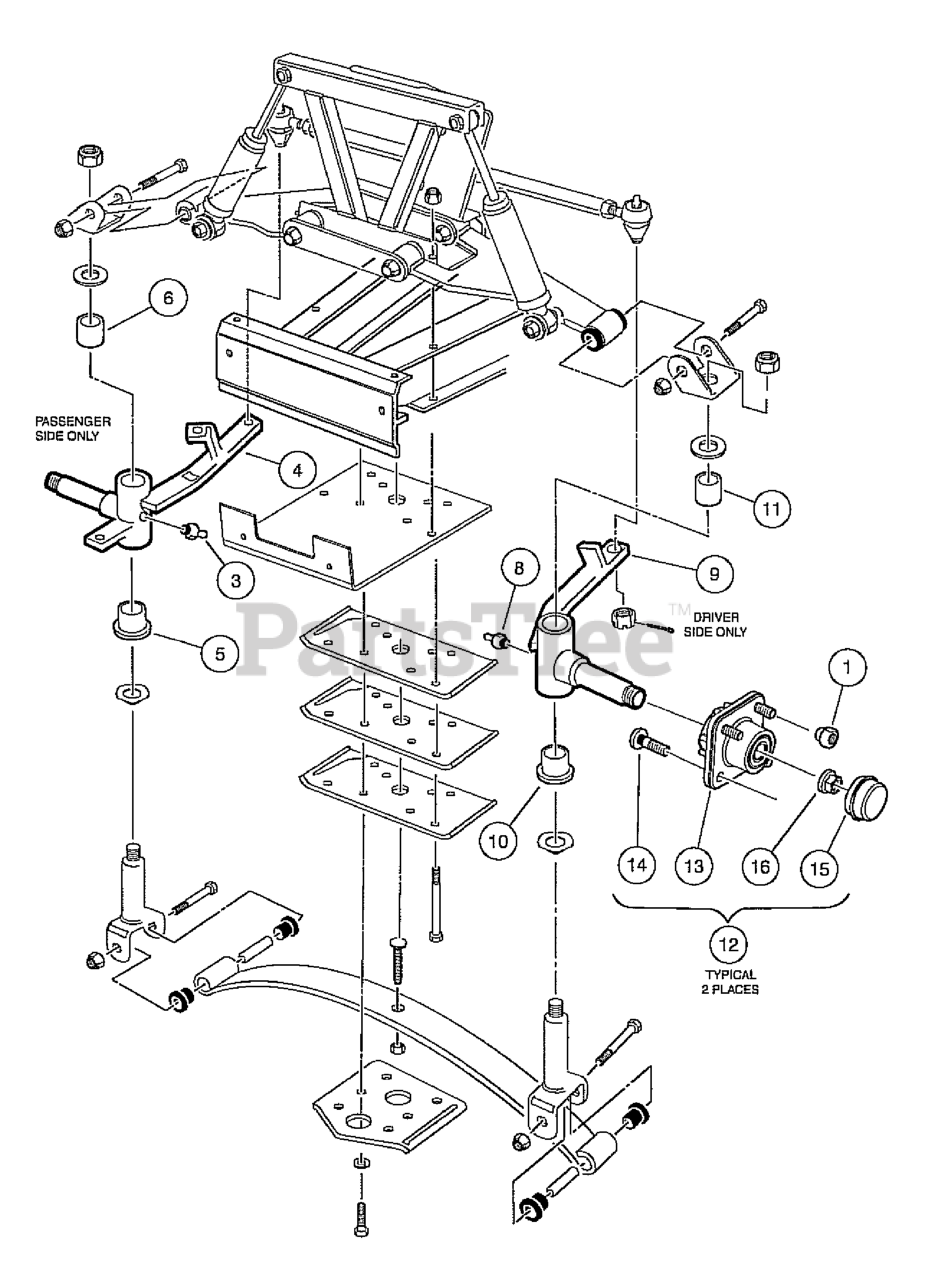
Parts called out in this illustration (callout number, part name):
1	NUT 1/2-20 LUG
2	ASM, SPINDLE, RH, EXT
3	FITTING, 1/4-28 THRD FRM GREAS
4	Subasm, Spindle, RH, EXT
5	BUSHING, FLANGED BROZE
6	BUSHING BRONZE SPINDLE
7	ASM, SPINDLE, LH, EXT
8	FITTING, 1/4-28 THRD FRM GREAS
9	Subasm, Spindle, LH, EXT
10	BUSHING, FLANGED BROZE
11	BUSHING BRONZE SPINDLE
12	REPLACEMENT KIT, FRONT HUB
13	REPLACEMENT KIT, FRONT HUB
14	LUG STUD, 1/2-20 UNF, 4037 STL
15	CAP, FRONT HUB
16	HEX NUT, LOCKING FLANGE, M14X2
